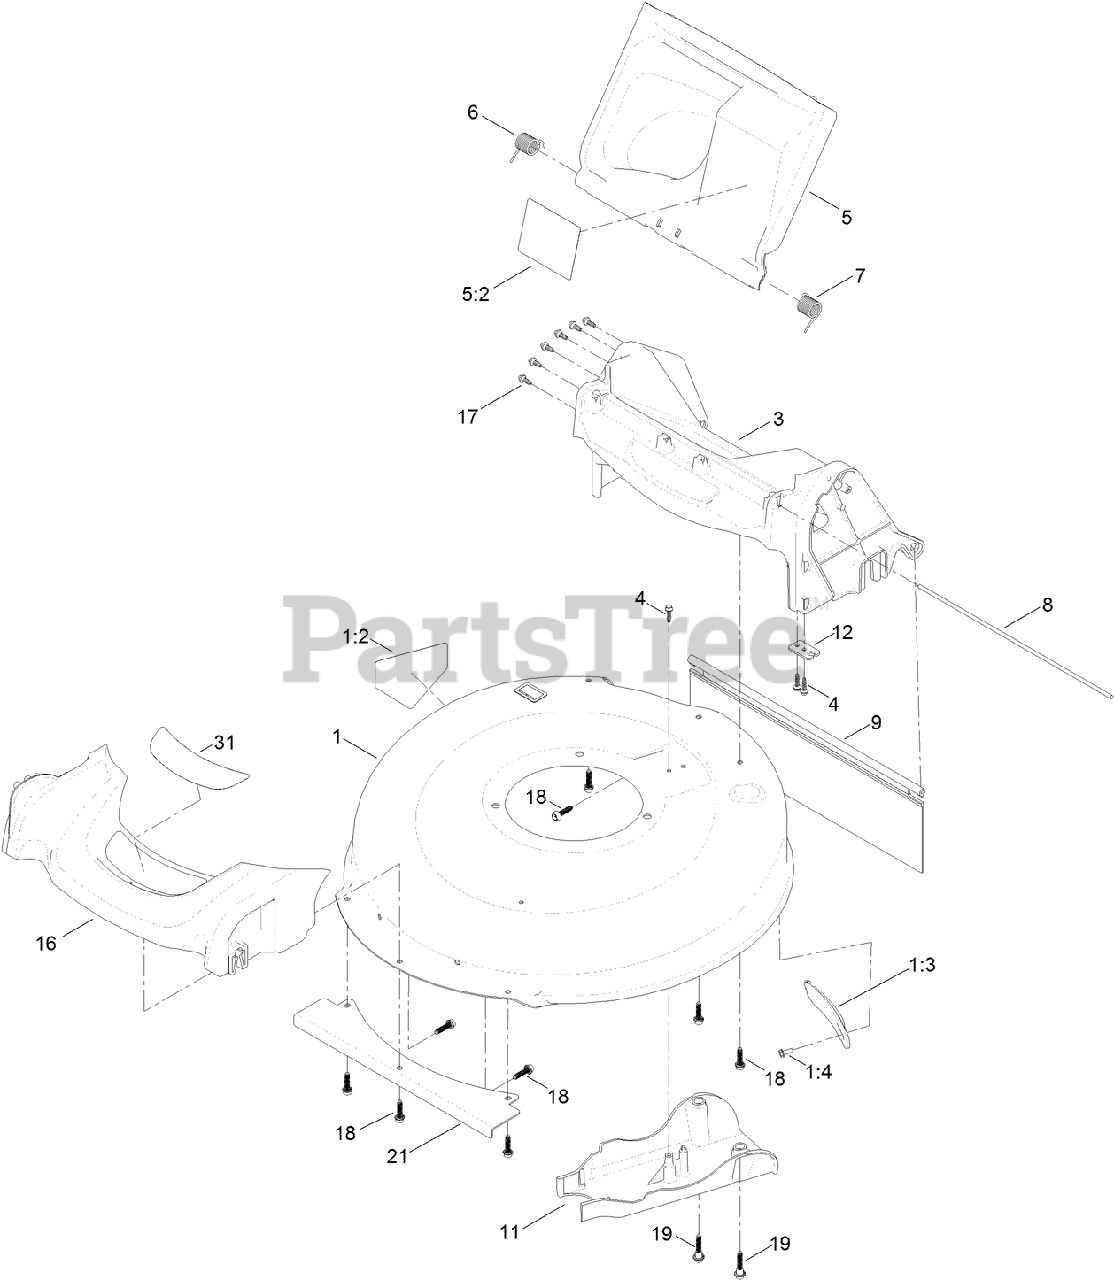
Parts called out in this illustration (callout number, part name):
1	HOUSING ASM
1:2	DECAL-DANGER
1:3	COVER-BELT
1:4	SCREW-TAPTITE
4	SCREW-HWH
5	REAR DEFLECTOR ASM
5:2	DECAL-WARNING
6	SPRING-TORSION
7	SPRING-TORSION
8	ROD-DOOR
9	SHIELD-TRAILING
11	COVER-BELT
12	BRACKET-CABLE
16	BUMPER
18	SCREW-FLANGE, PLASTIC
19	SCREW-SHOULDER, HHF
21	SHIELD-FRONT
31	DECAL-DECK
